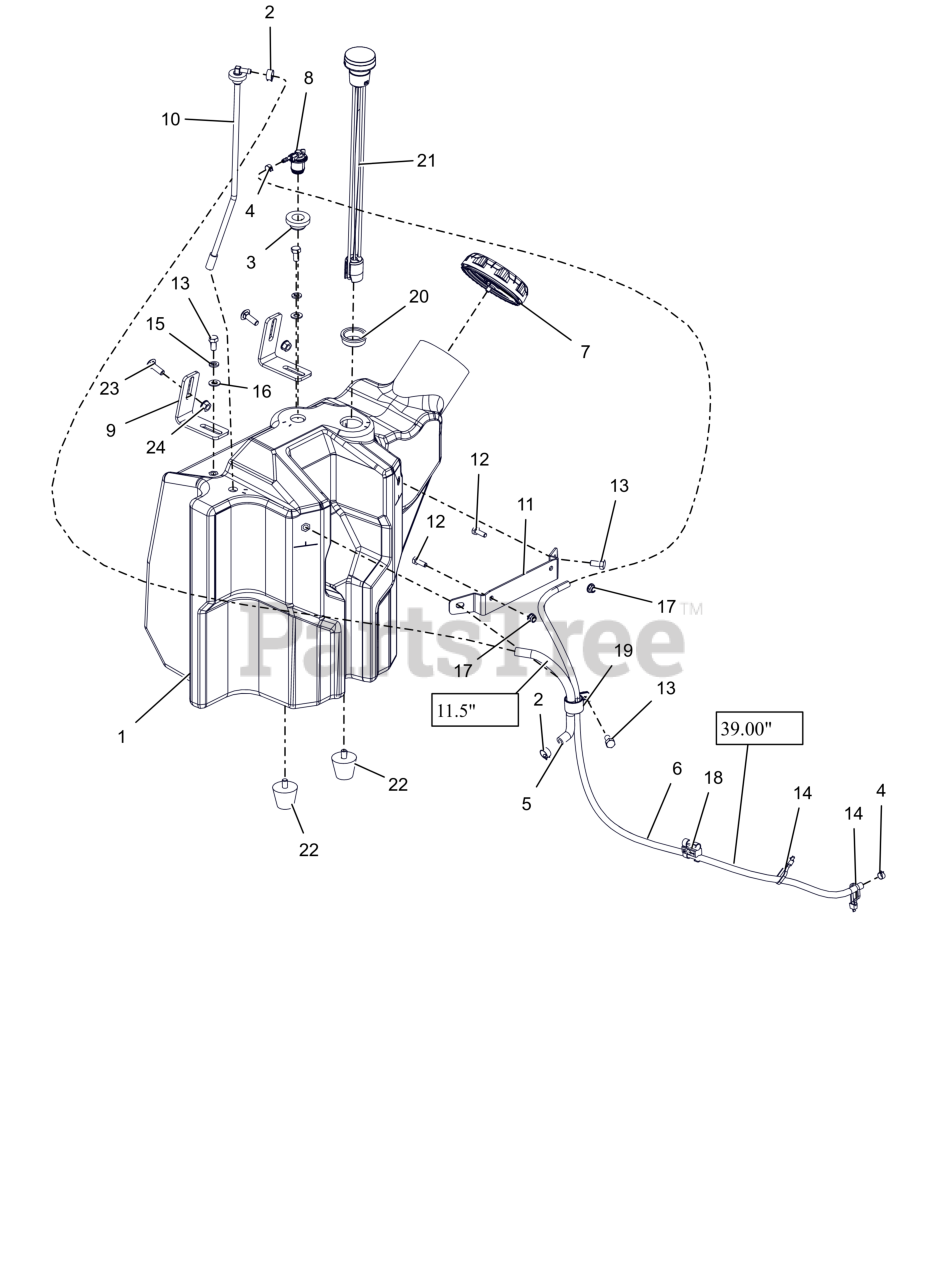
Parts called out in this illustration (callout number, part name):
1	ASM, 32-36" PROSTANCE FUEL TANK
2	CLAMP, FUEL LINE
3	GROMMET, REMOTE VENT NITRILE
4	CLAMP-HOSE, SPRING .188
5	1 INCH OF HOSE, .25 LOW-PERM BULK GAS
6	HOSE, .188 LOW-PERM BULK GAS
7	CAP, FUEL VENTIN AUTOLOCK
8	VALVE, COMBINATION VENT 3/16
9	BRKT, TANK HOLDDOWN
10	ASM, PROSTANCE FUEL LINE PICK-UP
11	BRKT, OVERFLOW MTG (BLACK)
12	BLT, HEX .25-20X.75 G5 ZCC
13	BLT, HEX .31-18X.625 G5 ZCC
14	CABLE TIE, .15 X 8.50
15	WSHR,LK-REG .312X.078 ZCC
16	WSHR,FLT .344X.688X.065 ZCC
17	NUT,NYL-FLG .25-20 GF ZCC
18	CLIP, T, .38-.50
19	CLAMP, COUSHIONED STEEL REV
20	GROMMET, FUEL GAUGE
21	GAUGE, REMOTE FUEL SEALED 15"
22	BUMPER, STUD MOUNTED CONE SHAPED
23	BLT,RHSN .31-18X1.00 G5 ZCC
24	NUT,LK-CTR-FLG .31-18 GF ZCC
